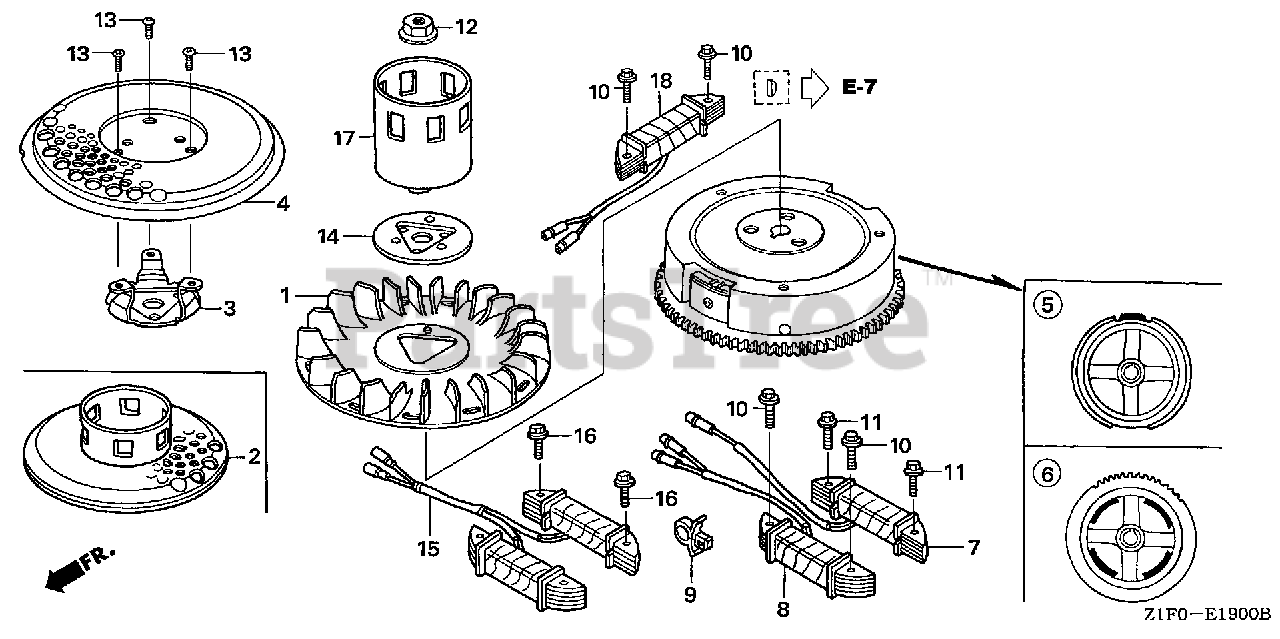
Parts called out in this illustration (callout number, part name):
1	FAN, COOLING
6	FLYWHEEL
10	BOLT, FLANGE (6X28) (CT200) Use up to Engine SN 1530314.
12	NUT, SPECIAL (16MM)
17	PULLEY, STARTER
18	COIL ASSY., CHARGE
